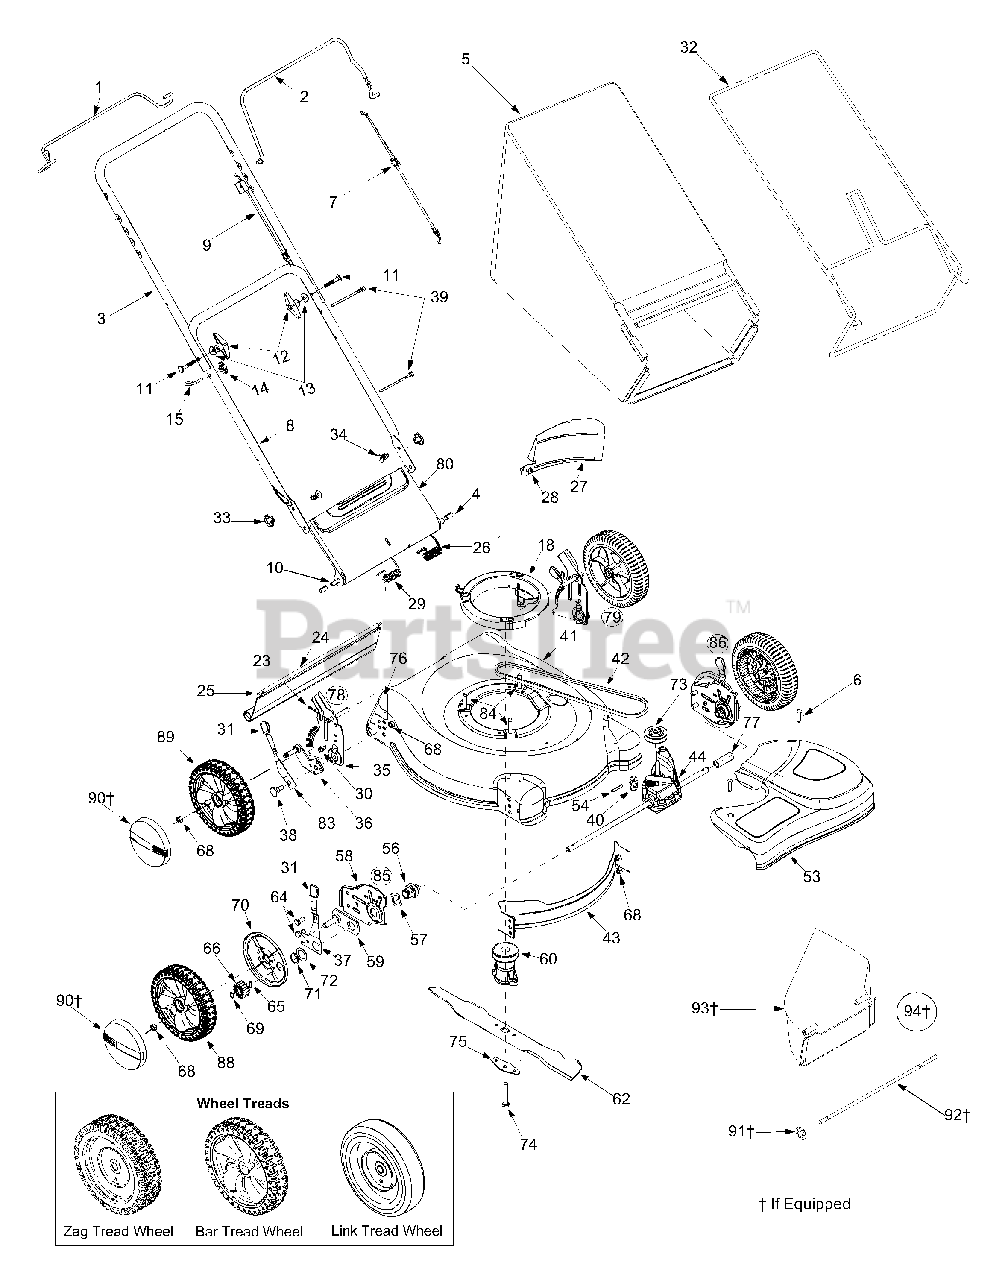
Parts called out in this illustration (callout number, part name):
1	Lower Bail Handle
4	Spacer .390OD x .810ID x .950"
5	Grass Bag
6	Shoulder Screw
7	Control Cable: 37.75"
9	Drive Cable
10	Rear Door Pivot Rod
11	Carriage Bolt
12	Handle Knob
13	Saddle Washer
14	Wing Nut
15	Rope Guide
18	Engine Spacer Assembly
23	Hairpin Clip
24	Rear Trail Shield
25	Trail Shield Wire
26	Torsion Spring LH
28	Scr. AB 1/4-14 x 0.625"
29	Torsion Spring RH
30	Hex Scr. w/ Wash. 1/4-20 x 0.625"
31	Knob
33	Wing Nut
34	Hex Carriage Screw
35	Handle Bracket RH
36	Pivot Arm Assembly RH
37	Front Lever RH
38	Shoulder Screw
39	Cable Tie
40	Belt Tension Spring
41	Rear Discharge Deck: 21"
42	V-Belt
53	Front Drive Cover
54	Roll Pin
56	Bearing Assembly
57	Wave Washer
60	21" One Piece Blade Adapter
62	Mulching Blade w/ Star: 21"
64	Hex Screw
65	Dowel Pin
66	Gear 14T RH
68	Hex Nut
69	Snap Ring
70	Wheel Dust Cap
71	Snap Ring
72	Washer DD 1.5" O.D.
73	Input Pulley
74	Hex Bolt
75	Bell Blade Support
77	Slev. Spacer LH
78	Handle Brkt Assembly RH Compl.
79	Handle Brkt Assembly LH Compl.
80	RD Chute Door
83	Spring Lever
84	TT Screw
85	Height Adj. Assembly RH Compl.
86	Height Adj. Assembly LH Compl.
88	Front Wheel
89	Rear Wheel
90	Hub Cap
91	Nut: Spd.3125ID
92	Rod
93	Side Discharge Adapter
94	Chute Deflector Complete
